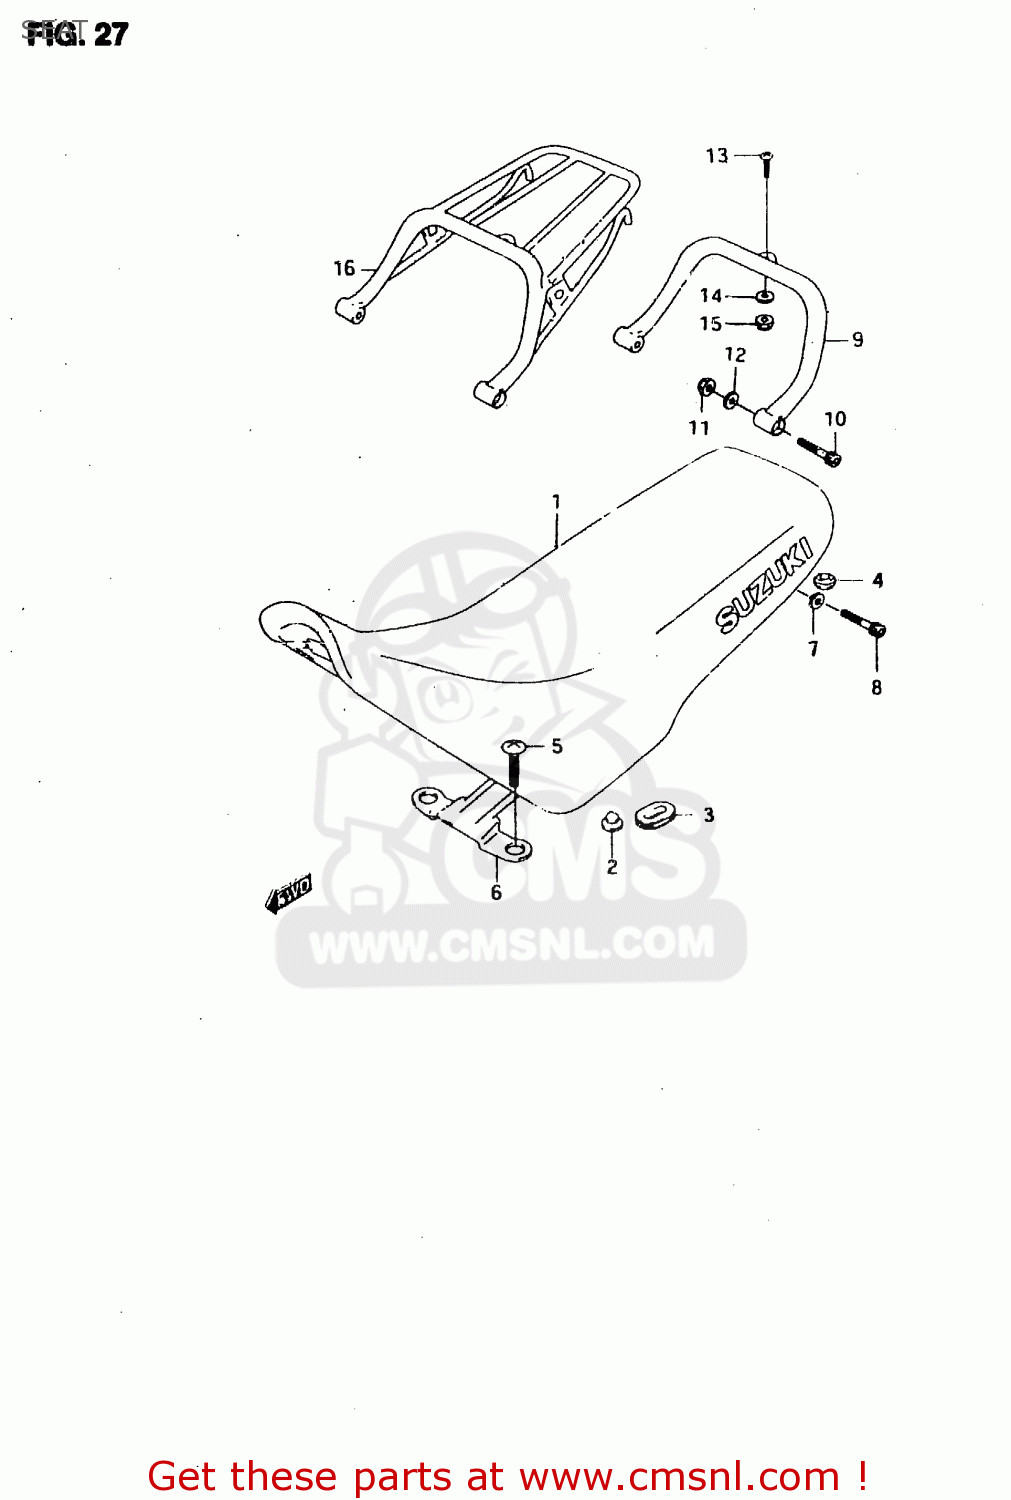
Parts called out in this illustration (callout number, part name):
1	SEAT SET
2	CUSHION
3	CUSHION
4	CUSHION
5	SCREW
6	PLATE
7	WASHER
8	BOLT
9	CARRIER SET
10	BOLT
11	NUT
12	WASHER
13	SCREW, 6X20
14	WASHER
15	NUT
16	CARRIER
